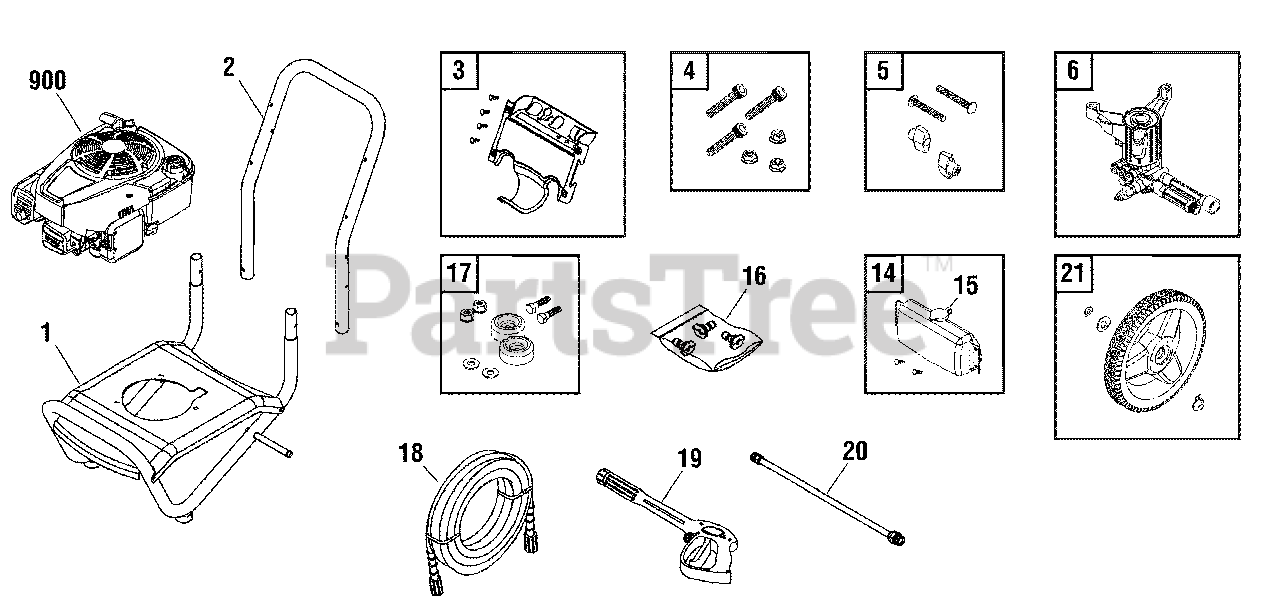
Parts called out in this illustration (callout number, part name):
4	KIT, Hardware Pump Mounting
5	KIT, Hardware Handle
14	TANK, Chemical
15	CAP, Chemical Tank
16	KIT, QC Nozzles
17	KIT, Vibration Mount
18	HOSE
19	GUN
20	EXTENSION, QC
900	* ENGINE
